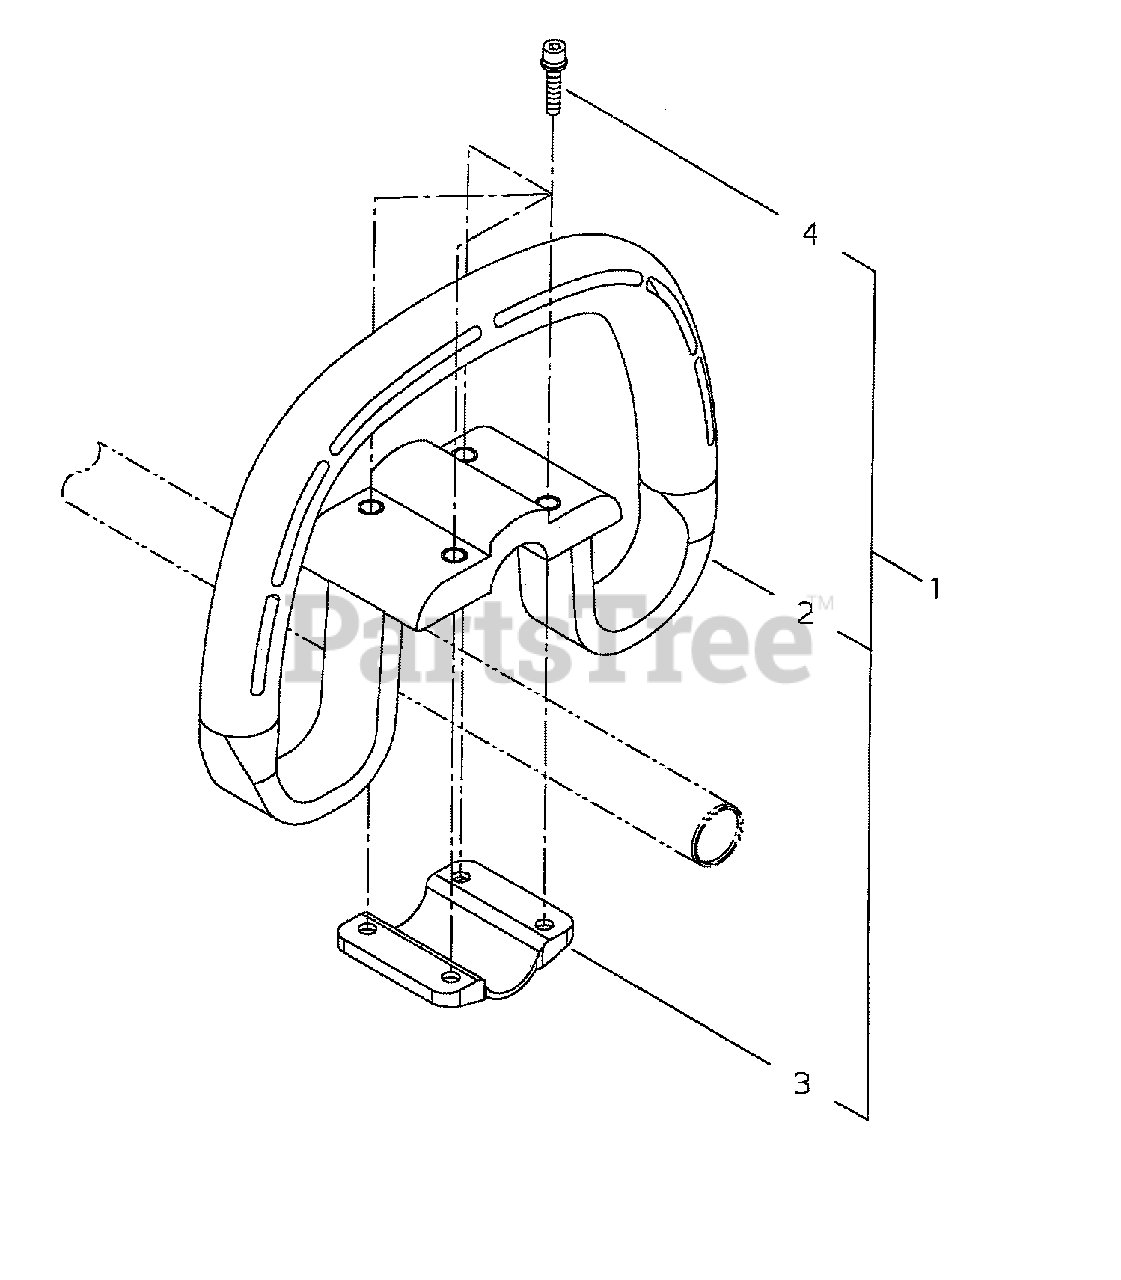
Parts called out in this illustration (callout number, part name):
1	HANDLE ASSY
2	HANDLE
3	CLAMP - LOWER
4	SCREW - 5X25
